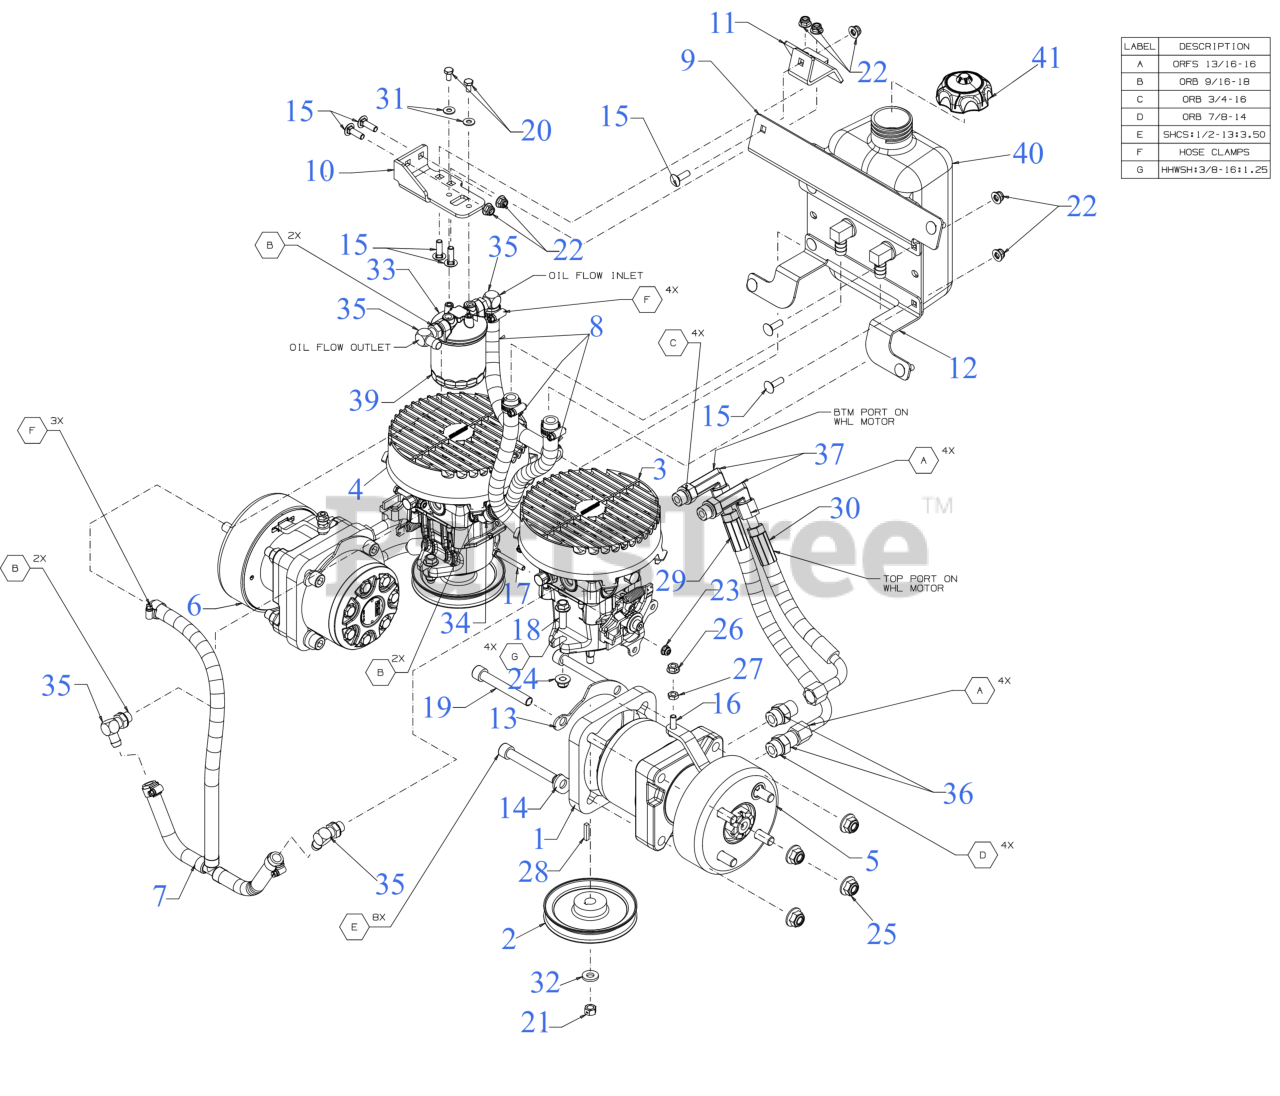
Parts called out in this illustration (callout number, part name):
1	WHEEL SPACER MOTOR
2	PULLEY-HYDRO PUMP
3	HYDRO PUMP (RH)
4	HYDRO PUMP (LH)
5	HYDRO MOTOR (RH)
6	HYDRO MOTOR (LH)
7	HYDRO DRAIN HOSE
7	HOSE CLAMP
8	HYDRO HOSE ASM 11"
9	OIL RESERVOIR BRACKET
10	FILTER MOUNT BRACKET
11	BRAKE CABLE MOUNT BRACKET
12	OIL RESERVOIR BRACKET (LOWER)
13	WHEEL MOTOR SHIM PLATE
14	WHEEL MOTOR LOWER SHIM PLATE
15	CARRIAGE BOLT 5/16-18 x 1.00
16	SCREW 5/16-18 x 1.0 GR5
17	SCREW 1/4-20 x 2 GR5
18	SCREW 3/8-16 x 1.25 GR5
19	HEX CAP SCREW 1/2"-13x3.5
20	SCREW 1/4-20X.5 GR5
21	HEX NUT
22	FLANGE LOCK NUT 5/16-18
23	FLANGE LOCK NUT
26	HEX FLANGE NUT
27	HEX NUT
28	SQUARE KEY 3/16 x 1.00
29	HYDRO PUMP HOSE
30	HYDRO PUMP HOSE - TOP
31	FLAT WASHER
32	FLAT WASHER
33	OIL FILTER ADAPTER
34	45 DEGREE FITTING (6 ORB X-8 BEAD)
35	ELBOW FITTING
36	HYDRO FITTING 8 ORFS x 10 ORB
37	ELBOW FITTING
39	HYDRAULIC FILTER
40	HYDRO OIL TANK (1 GAL)
41	HYDRO OIL TANK CAP
